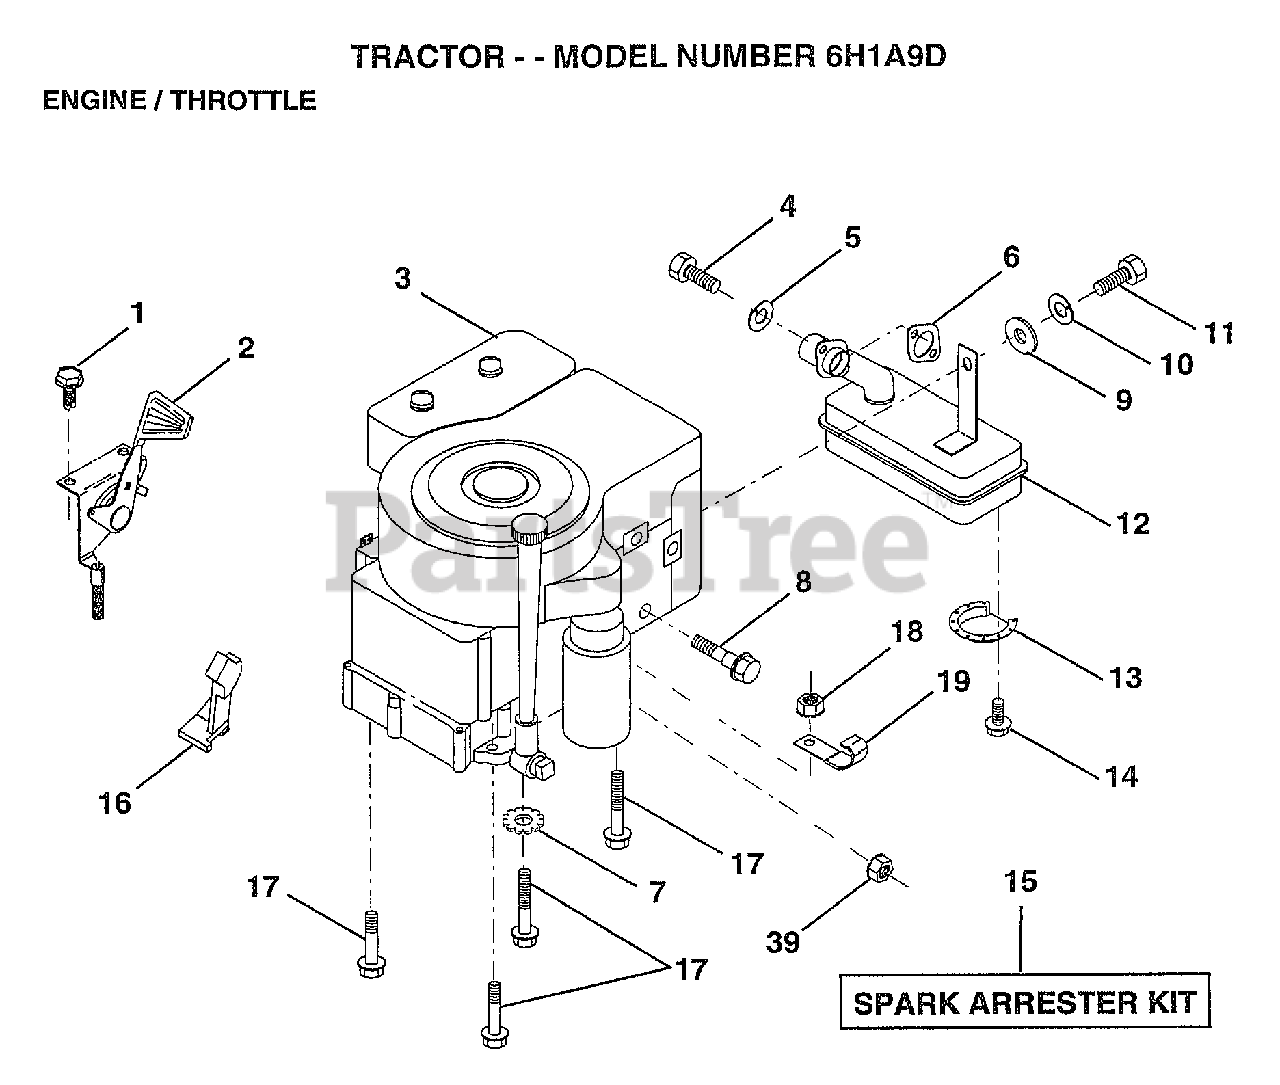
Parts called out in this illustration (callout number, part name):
1	SCREW.1/4-20X1/2
4	SCREW
5	LOCKWASHER
6	GASKET ENG 1 313 LD TIN PLATED
7	LOCKWASHER
8	BOLT T
10	LOCKWASHER
12	MUFFLER
13	DEFLECTOR.222573
16	"STOP,DASH THROTT"
17	SCREW LT
18	NUT
19	CLIP T
39	NUT
